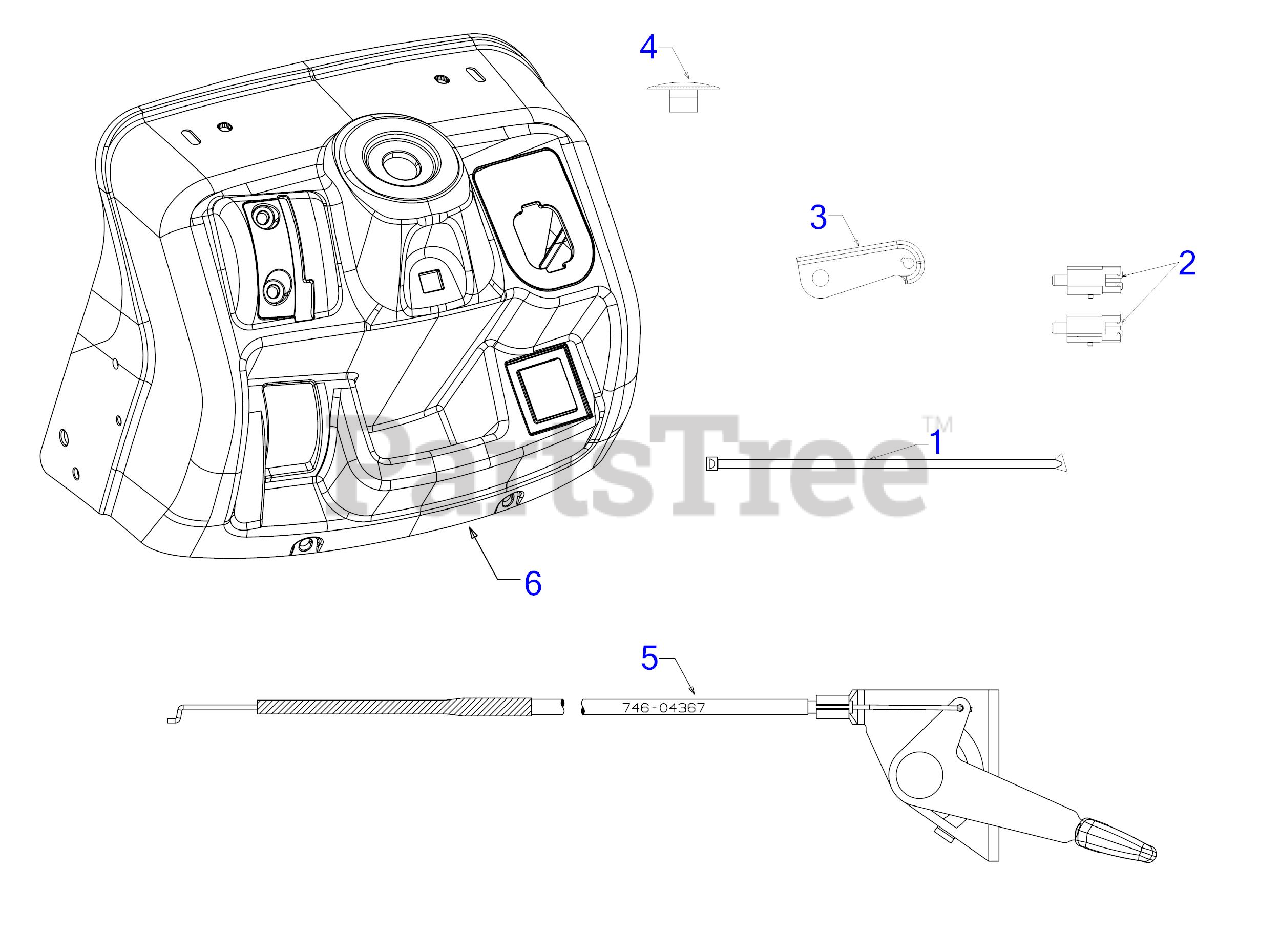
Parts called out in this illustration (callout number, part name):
1	7" CABLE TIE
2	INTERLOCK SWITCH (NO/NC)
3	LATCH SPEED BRACKET
4	CHOKE PLUG
5	THROTTLE CABLE 28" x 1.1
6	UPPER DASH
